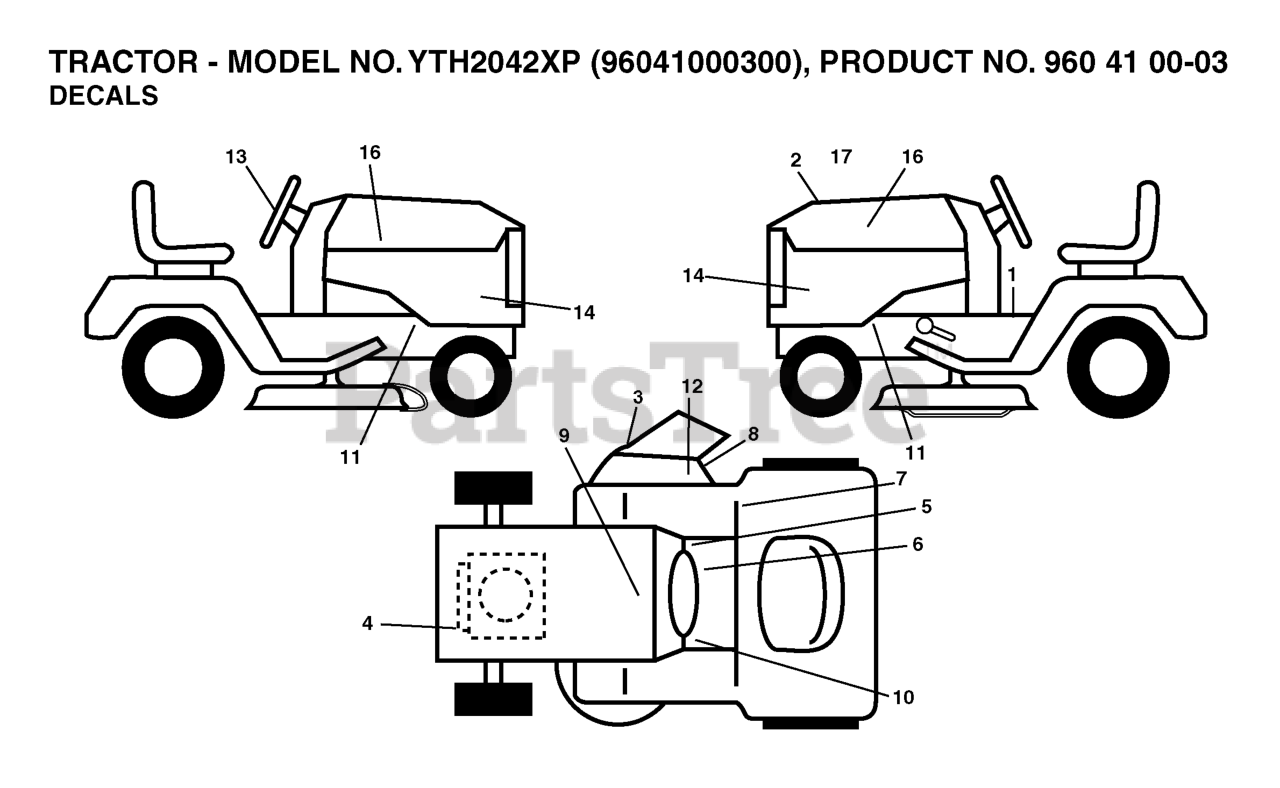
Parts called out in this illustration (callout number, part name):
1	LABEL
2	DECAL.HOOD.TOP.INSERT.
3	DECAL, DEFLECT WARNING
4	DECAL
5	DECAL PARK BRAKE
6	DECAL
7	DECAL
8	DECAL V BELT SCHEMATIC
9	DECAL BTRY SYMBOLS
10	DECAL
12	DECAL.INTERNATIONL.CUTFINGER
13	DECAL.STEERING.HUSQ.BLUE
16	DECAL.HOOD.NAMELOGO.HUSQ
